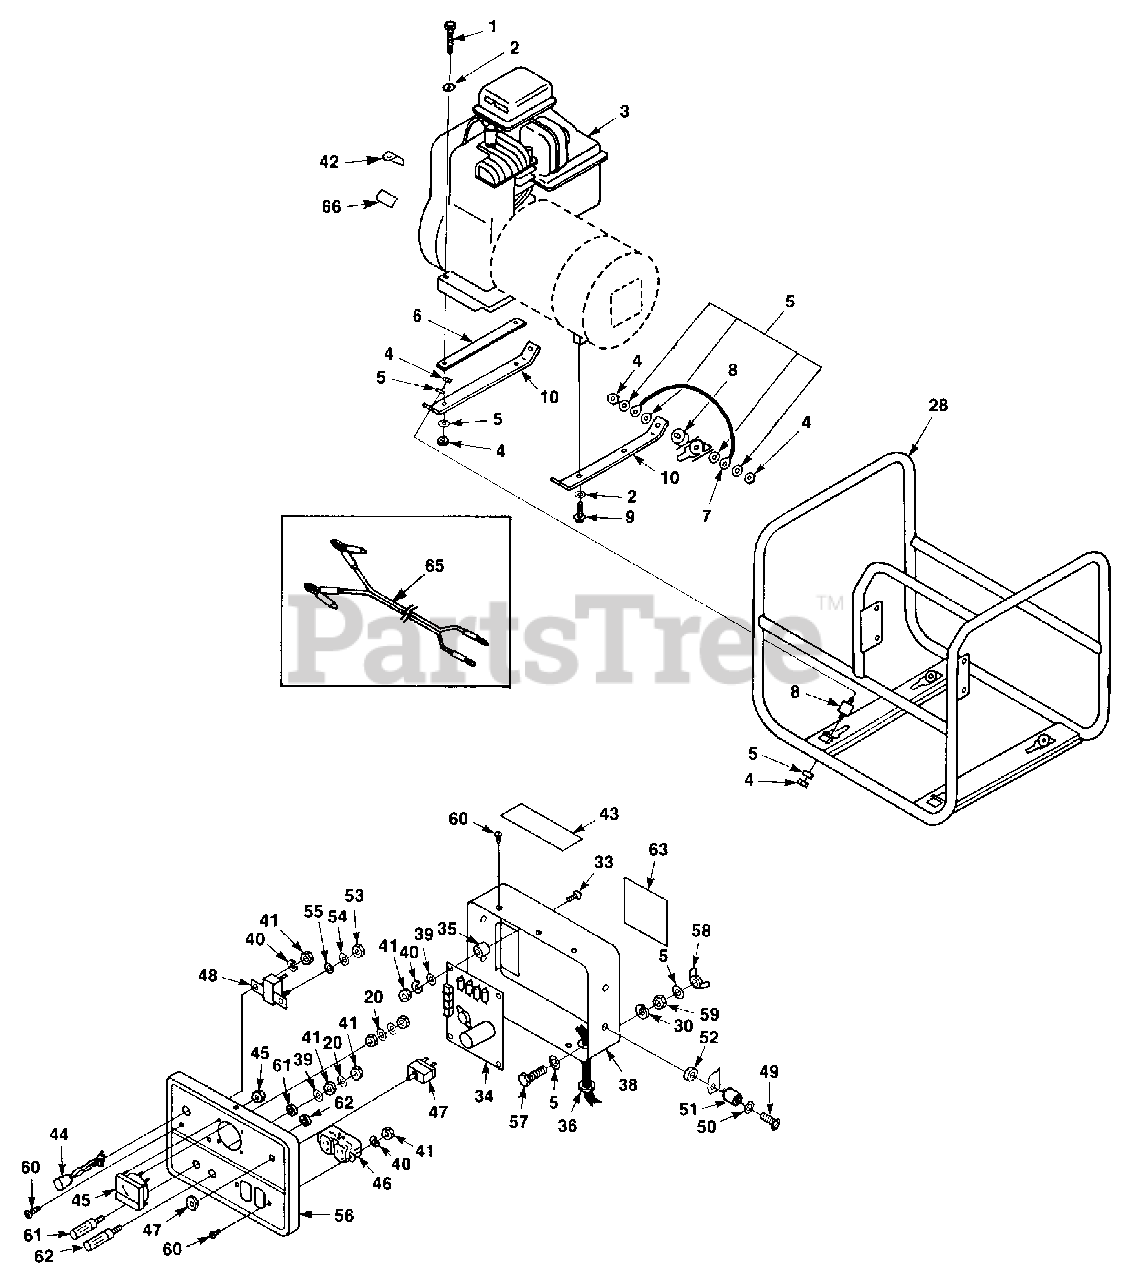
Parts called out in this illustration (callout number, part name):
1	SCREW- (5/16-18 x 2") 170R18
2	WASHER- Lock Int. 5/16
3	ENGINE- 5 H.P. Briggs (170B16)
4	NUT- Hex 5/16-18
5	WASHER- Int. 5/16
6	SPACER (170B16)
7	STRAP- Ground
8	ISOLATOR- Vibration
9	SCREW- Hex taptite 5/16-18 x 1"
10	SUPPORT- Engine & Generator
20	WASHER- Lock int. #8
28	ROLL CAGE
30	WASHER- Lock 5/16"
33	SCREW- Pan hd. #8-32 x 5/8"
34	VOLTAGE REGULATOR
35	SPACER- 1/4"
36	GROMMET
38	CONTROL BOX
39	WASHER- Flat #8
40	WASHER- Lock #8
41	NUT- Hex 8-32
42	BRACKET- Lite (170R18)
43	DECAL- Warning
44	PILOT LITE
45	VOLTMETER
46	RECEPTACLE- Duplex
47	BREAKER Circuit (AC) (170R18)
48	BREAKER- Circuit (DC)
49	SCREW- Pan Hd. 1/4-20 x 3/4"
50	WASHER- Flat 1/4"
51	SLEEVE- Grommet
52	GROMMET- Isolator
53	NUT- Hex 10-32
54	WASHER- Flat #10
55	WASHER- Lock #10
56	CONTROL PANEL
57	SCREW- Hex hd. 5/16-18 x 1"
58	NUT- Wing 5/16-18
59	NUT- Hex 5/16-18
60	SCREW- Pan hd. 8-32 x 3/8"
61	POST- Binding (Black)
62	POST- Binding (Red)
63	DECAL- Caution
65	LEAD- D.C.
66	DECAL- Low Oil (170R18)
